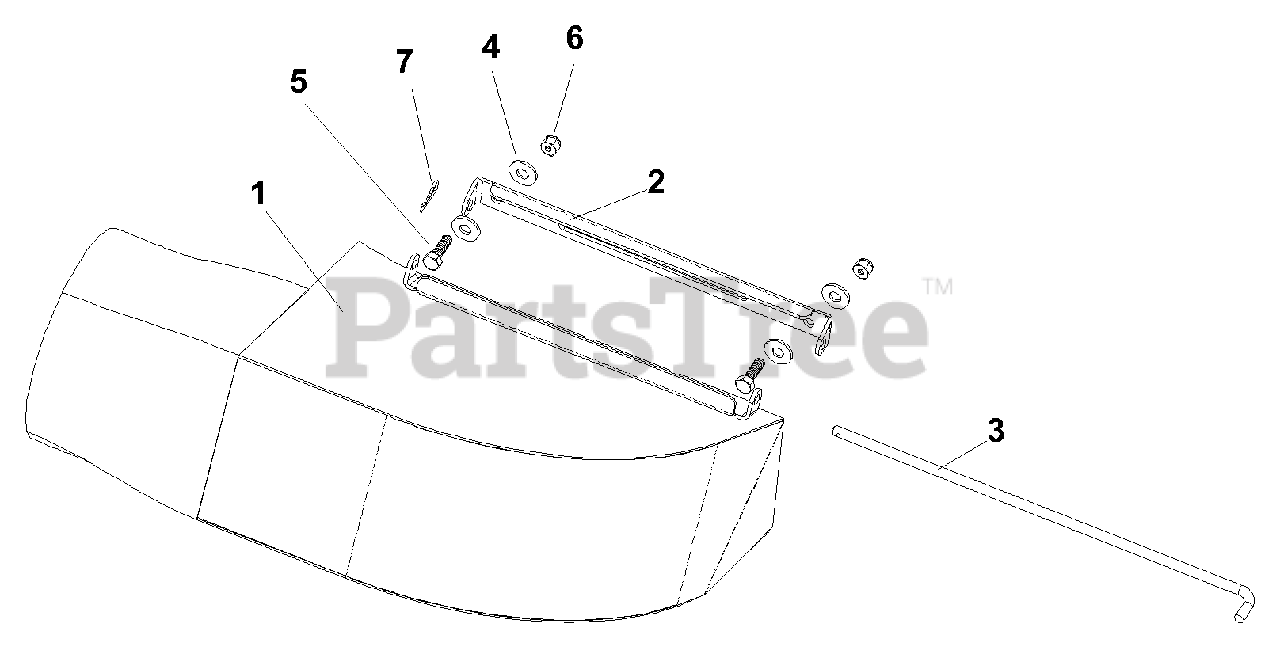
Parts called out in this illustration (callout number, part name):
1	Boot - Gen I
1	Boot - Gen II & Gen II - 72" deck
2	Deck bracket
3	Boot rod, 14"
4	Washer, 5/16
5	Bolt, 5/16-18 x 1
6	Nut, 51/6-18, nylock
7	Cotter pin, #13
